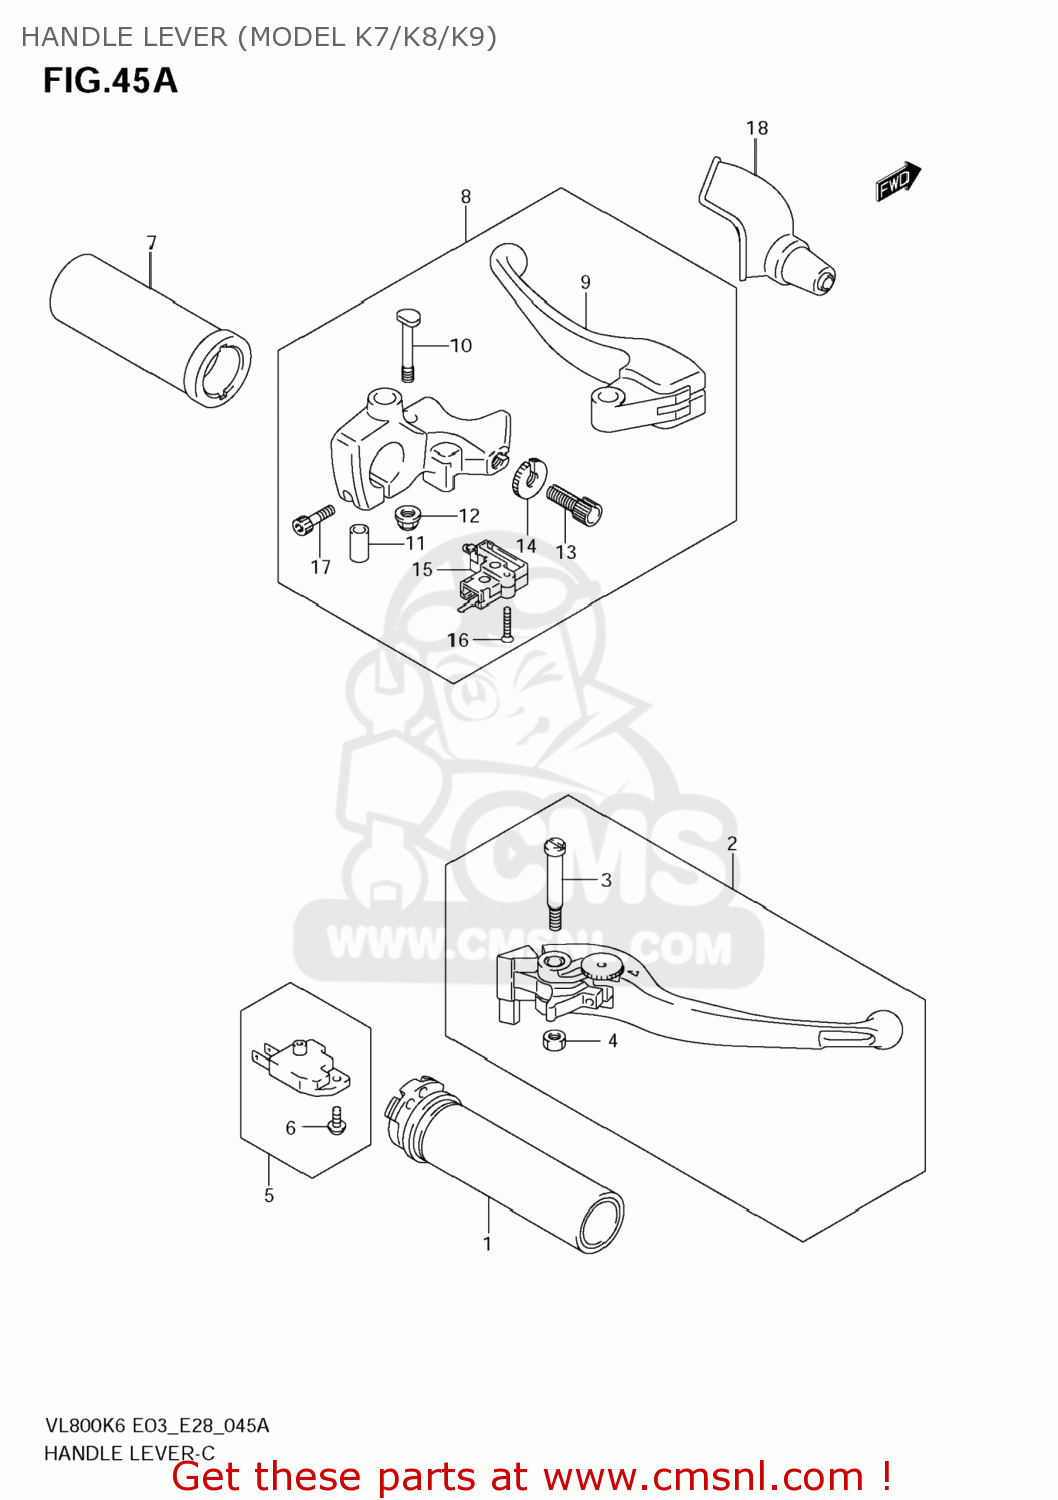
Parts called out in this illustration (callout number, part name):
1	GRIP,THROTTLE
2	LEVER ASSY,BRAKE
3	BOLT,PIVOT
4	NUT
5	SWITCH ASSY,ST
6	SCREW
7	GRIP,L
8	LEVER ASSY,CLU
9	LEVER,CLUTCH
10	BOLT,LEVER PIVOT
11	COLLAR
12	NUT
13	ADJUSTER,WIRE
14	NUT,LOCK
15	SWITCH,CLUTCH
16	SCREW
17	BOLT
18	COVER,CLUTCH LEVER
